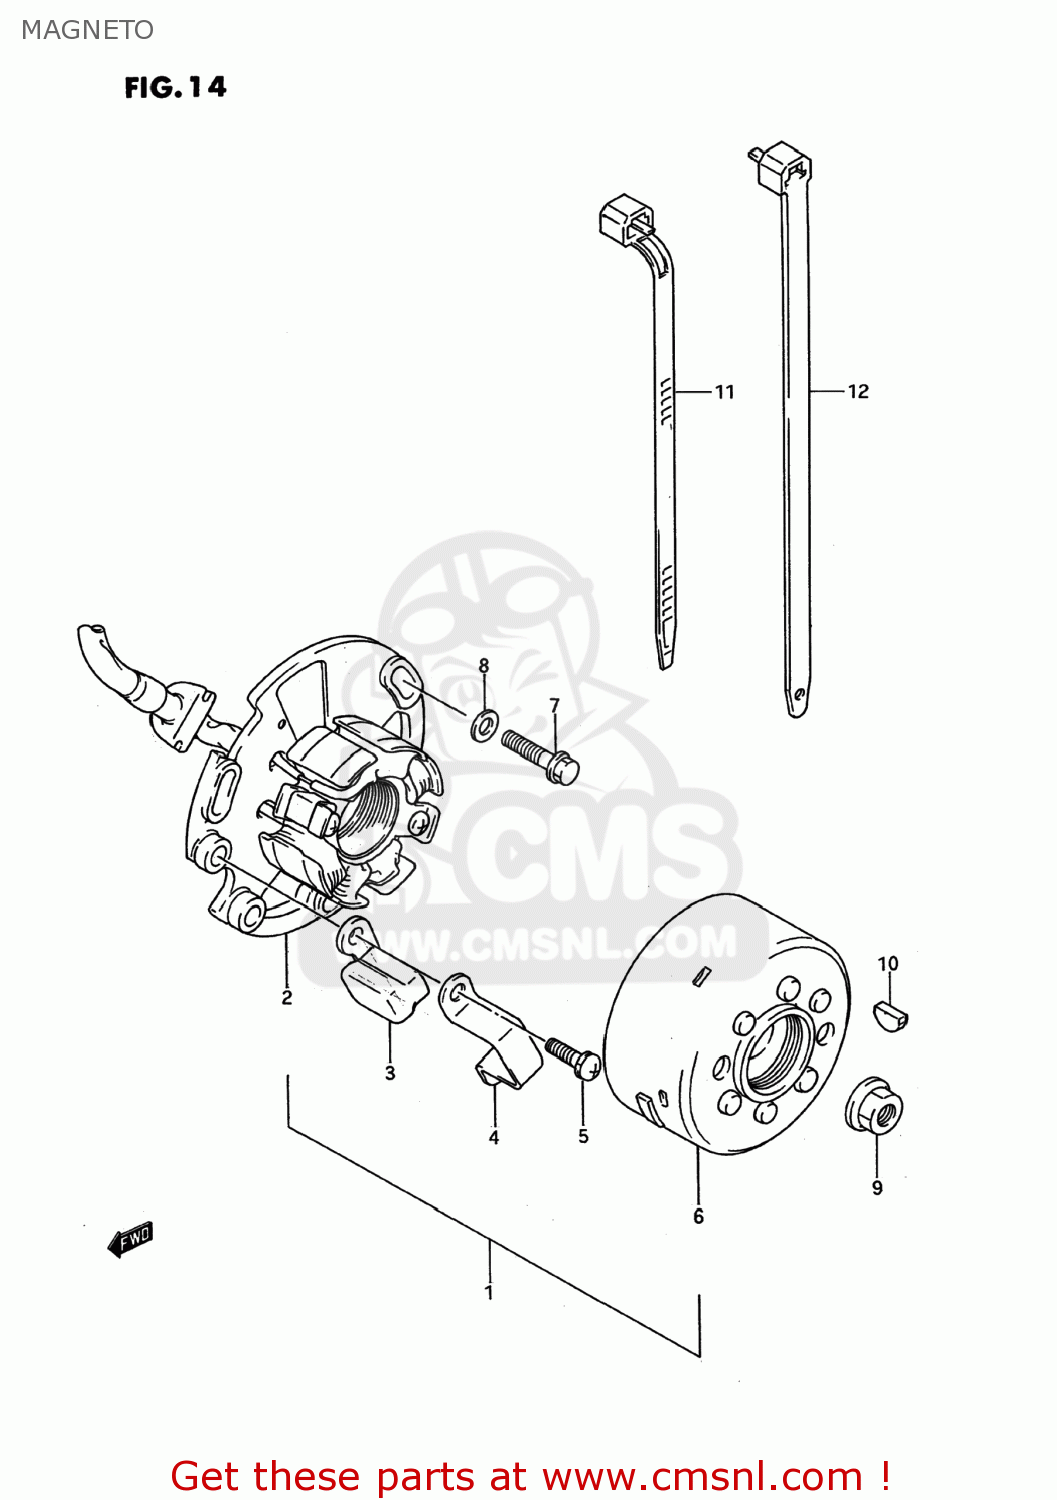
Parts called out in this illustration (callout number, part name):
1	MAGNETO ASSEMBLY
2	STARTER ASSY
3	COIL,PULSER
4	HOLDER,PICK UP COIL
5	SCREW
6	ROTOR ASSY
7	BOLT
8	WASHER
9	NUT
10	KEY
11	CLAMP(L:165)
12	CLAMP(L:235)
